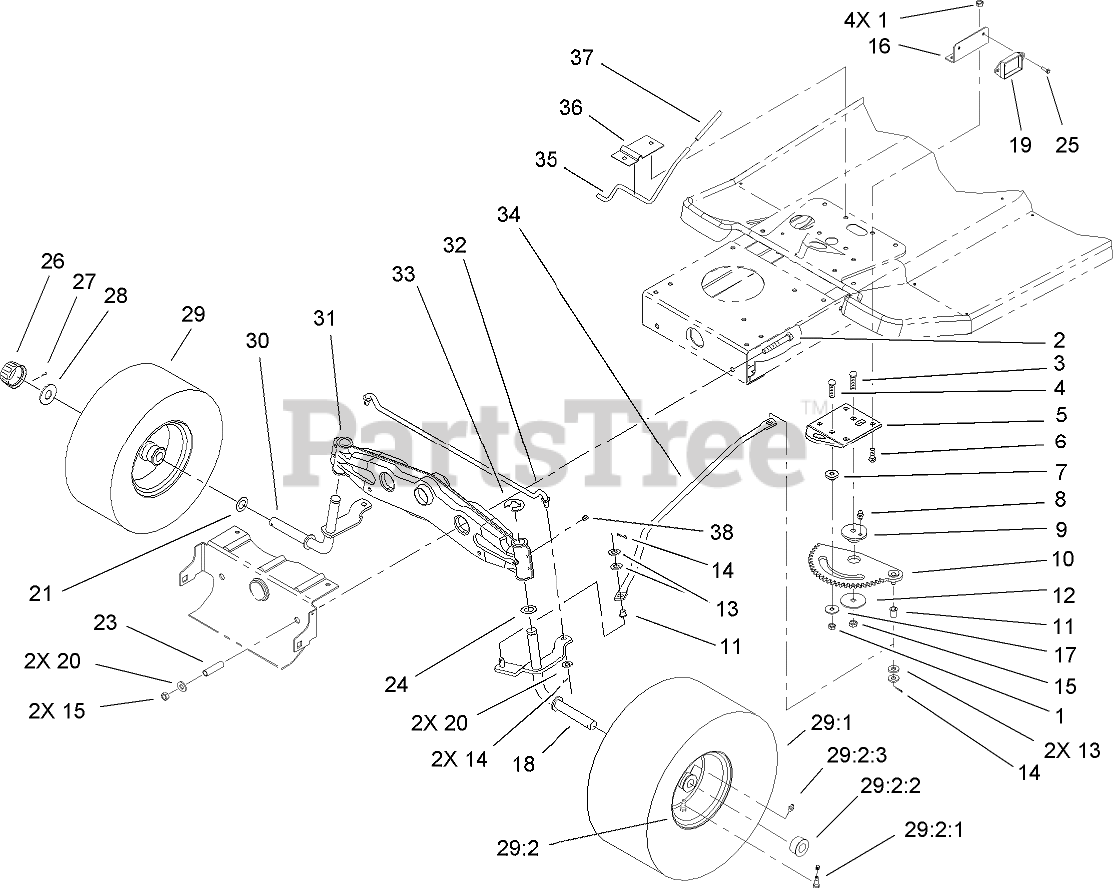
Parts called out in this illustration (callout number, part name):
1	NUT-LOCK, NI
2	SCREW-HH
3	SCREW-CARR
4	SCREW-CARR
5	BRACKET-RACK, STEERING
6	BOLT-CARR
7	SPACER-RACK, STEERING
8	FITTING-GREASE
9	BUSHING-ECCENTRIC
10	RACK-STEERING
11	BUSHING-FLANGED, NYLON
12	WASHER-BEARING
13	WASHER-FLAT
14	PIN-COTTER
15	NUT-LOCK, NI
16	BRACKET-MODULE
17	WASHER-PIVOT
18	LH SPINDLE ASM
19	MODULE
20	WASHER-FLAT
21	WASHER-THRUST
23	SPACER
24	WASHER-THRUST
25	SCREW-HWH
26	CAP-HUB
27	PIN-COTTER
28	WASHER-PLAIN
29	FRONT WHEEL and TIRE ASM
29:2	RIM ASM
29:2:1	STEM-VALVE
29:2:2	BEARING-WHEEL
29:2:3	FITTING-GREASE
30	RH SPINDLE ASM
31	FRONT AXLE ASM
32	TIE ROD-STEERING
33	E-RING
34	LINK-DRAG
35	ROD-BRAKE, PARKING
36	BRACKET-PARKING BRAKE
37	GRIP-BRAKE, PARKING
38	FITTING-GREASE
